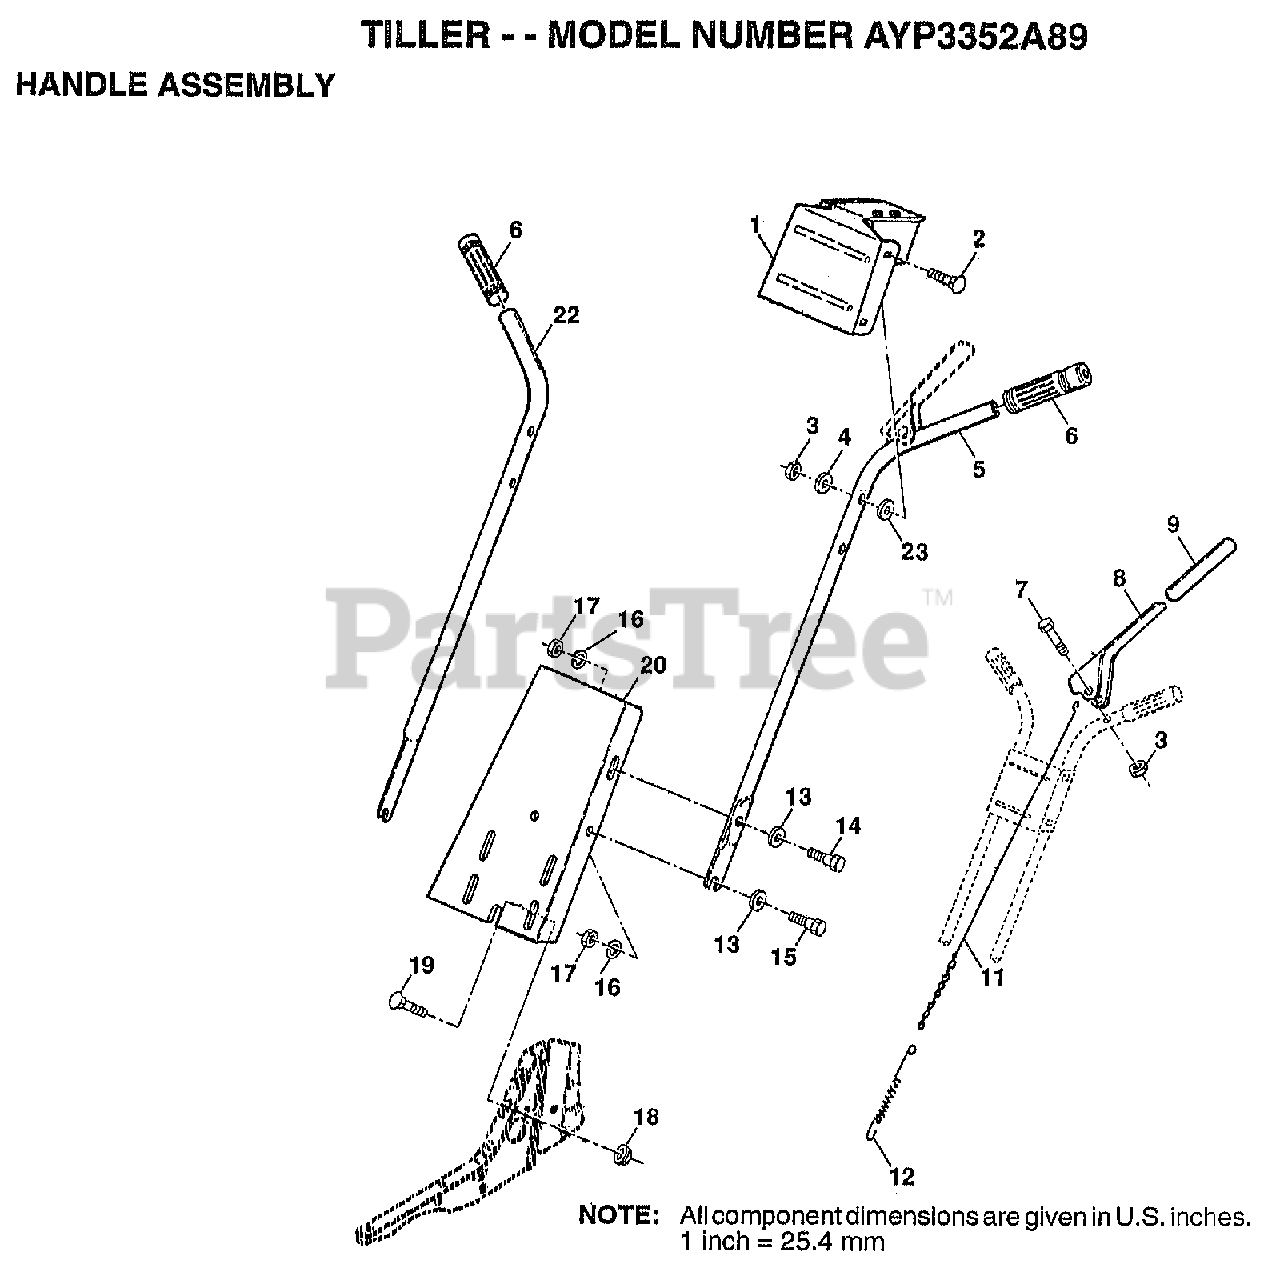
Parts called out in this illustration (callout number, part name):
1	HANDLE BRKT
2	BOLT
4	WASHER
5	HANDLE LH
7	BOLT.HEX.5/16-1.5
9	GRIP T
12	SPRING EXT TI
13	WASHER
15	BOLT
16	LOCKWASHER
17	NUT.HEX.5/16-18
18	NUT
19	BOLT
20	PANEL. HANDLE
22	HANDLE RH
23	WASHER
